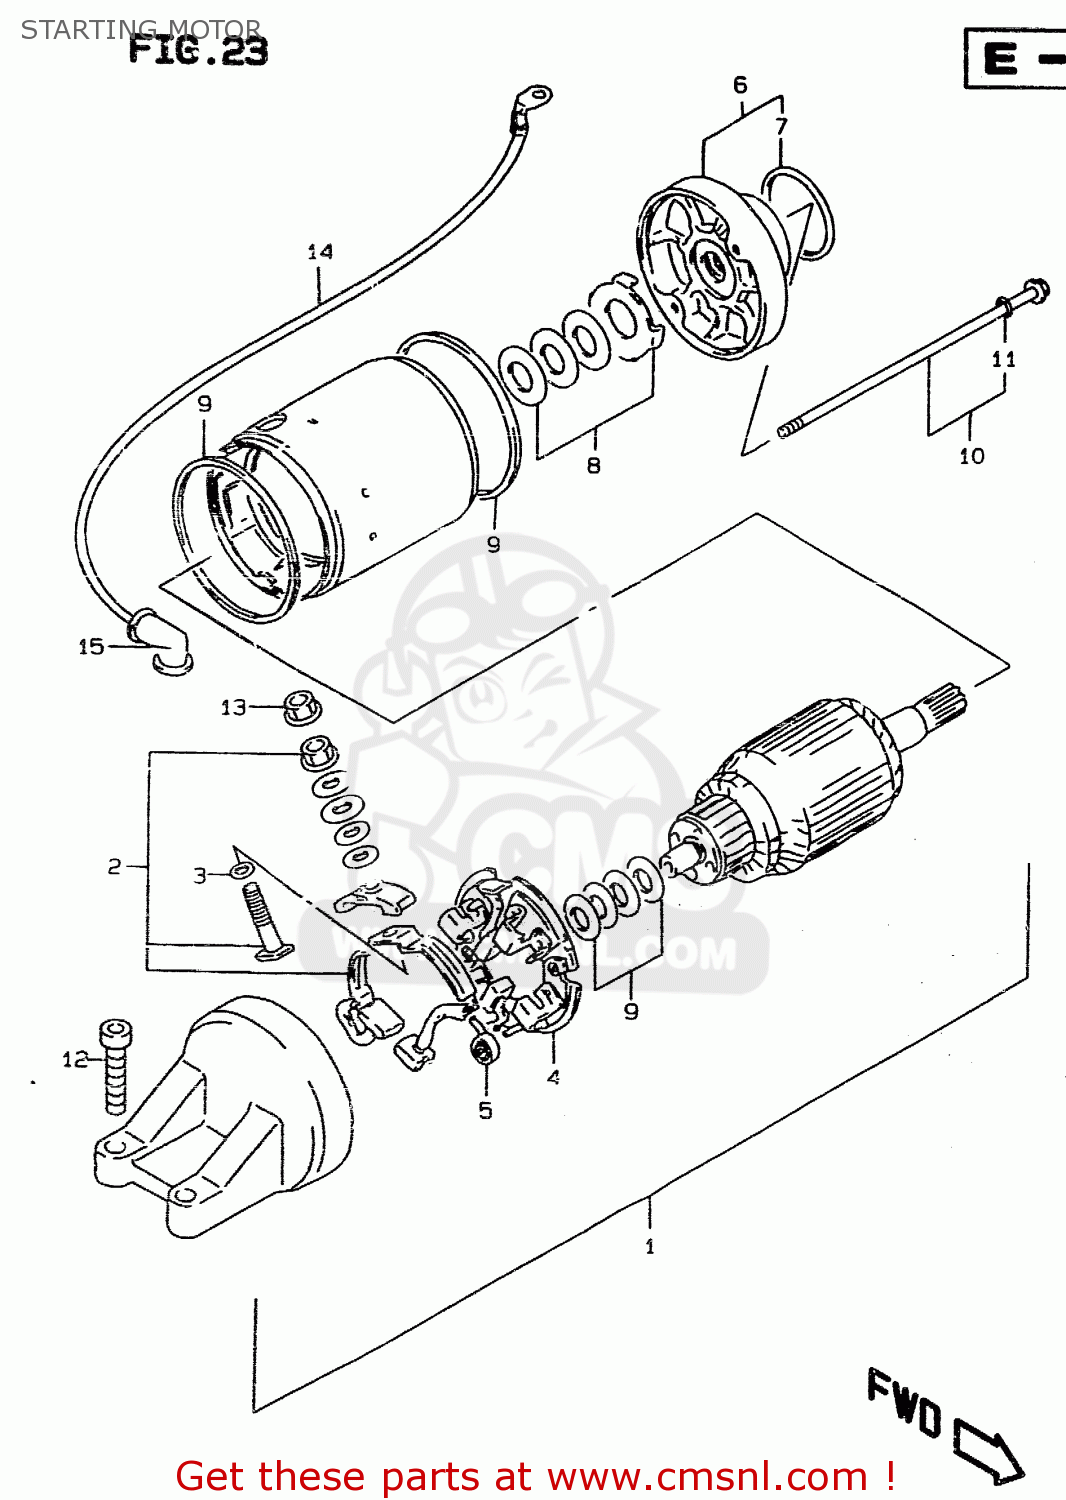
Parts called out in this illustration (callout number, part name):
1	MOTOR ASSEMBLY,STARTING
2	TERMINAL SET,BRUSH,PLUS
3	O RING
4	BRUSH,HOLDER SET
5	SPRING,BRUSH
6	BRACKET ASSEMBLY,FRONT
7	O RING
8	SHIM SET,STARTING MOTOR
9	O RING
10	BOLT SET,STARTING MOTOR
11	O RING
12	BOLT,OIL PAN
13	NUT
14	WIRE,STARTER MOTOR LEAD
15	CAP,STARTER MOTOR LEAD
